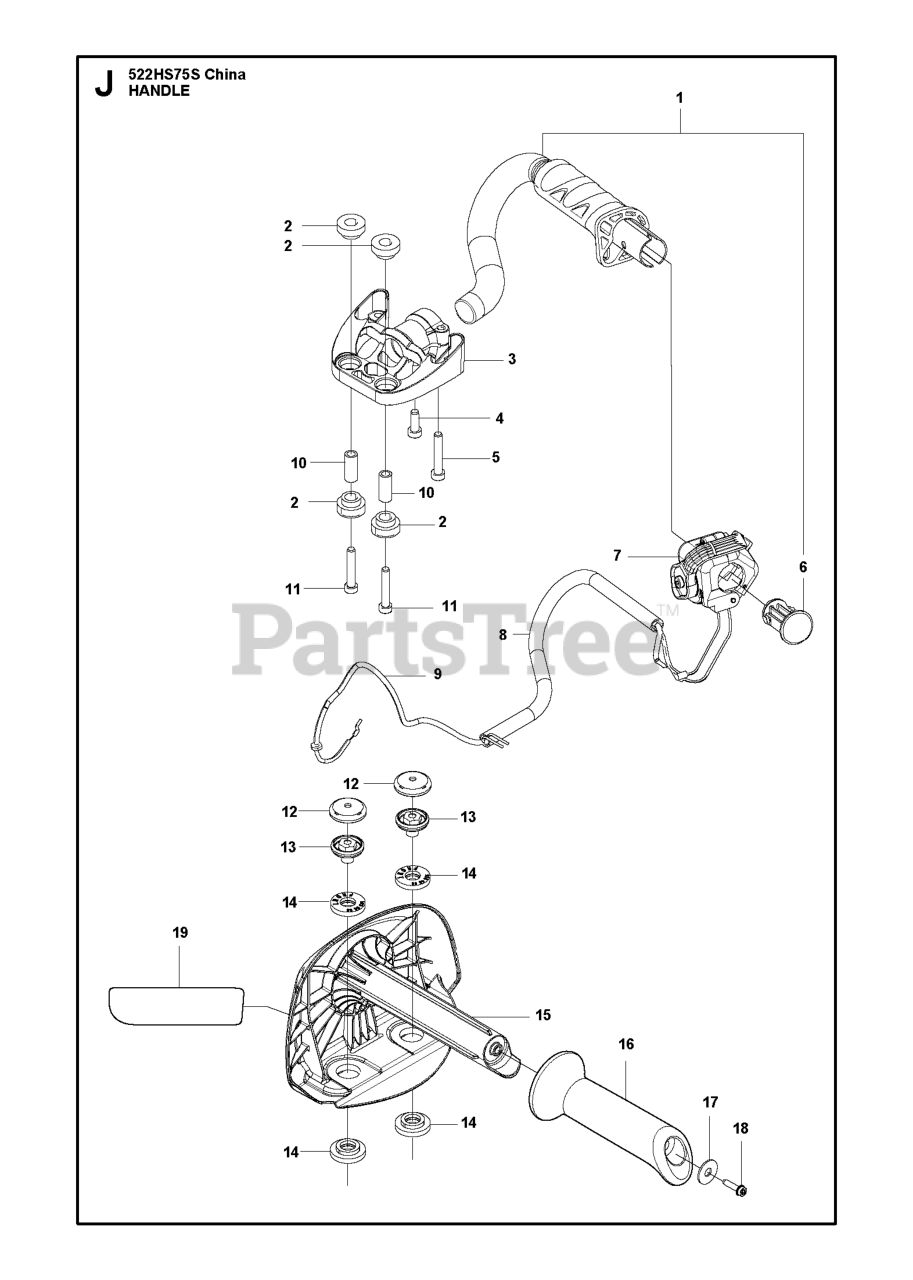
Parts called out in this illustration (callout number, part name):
4	BOLT M5X8 T27 10.9
14	ANTIVIBRATION ELEMENT
15	FRONT HANDLE HS HUSQVARNA-GREY
17	WASHER 5.3X15
